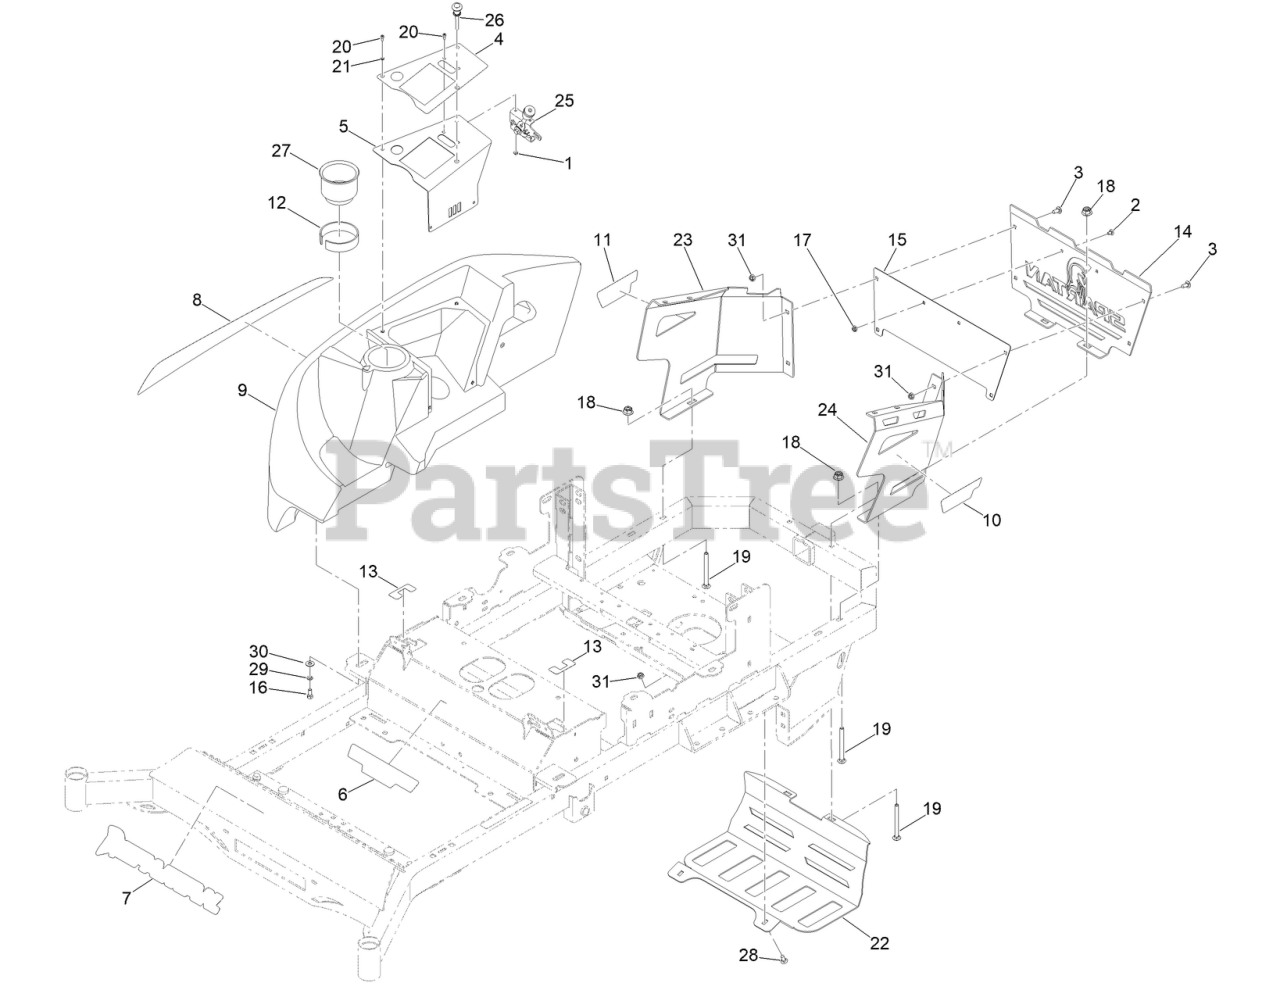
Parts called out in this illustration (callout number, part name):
1	NUT-LOCK
2	SCREW-CARR
3	BOLT-CARR
4	DECAL-CONSOLE
5	BRKT-CONTROL PANEL
6	DECAL- GT TRAC
7	DECAL- SPARTAN BLACKOUT LOGO
8	DECAL-POD RH
9	CONSOLE W/ CUPHOLDER
10	DECAL- MODEL
11	DECAL- MODEL
12	TAPE-FOAM
13	DECAL-MOTION CONTROL
14	PLATE - ENGINE COWLING
15	PLATE -BACKER PLATE
16	SCREW-HH
17	1/4-20 HEX FLANGE NUT
18	3/8-16 NYLON INSERT FLANGE L/NUT YZ
19	3/8-16 X 4 CARRIAGE BOLT ZINC
20	10-24 X 1/2 SOCKET C/S 18-8 SS
21	#10 SPLIT LOCKWASHER 18-8 SS
22	MUFFLER GUARD [BLK-TXT]
23	2021 RT/SRT ENGINE COWLING RIGHT
24	2021 RT/SRT ENGINE COWLING LEFT
25	MWR THROTTLE CABLE ASSY W / HANDLE
26	MWR CHOKE CABLE ASSM
27	CUP HOLDER
28	BOLT-CARR
29	WASHER-LOCK
30	WASHER-FLAT
